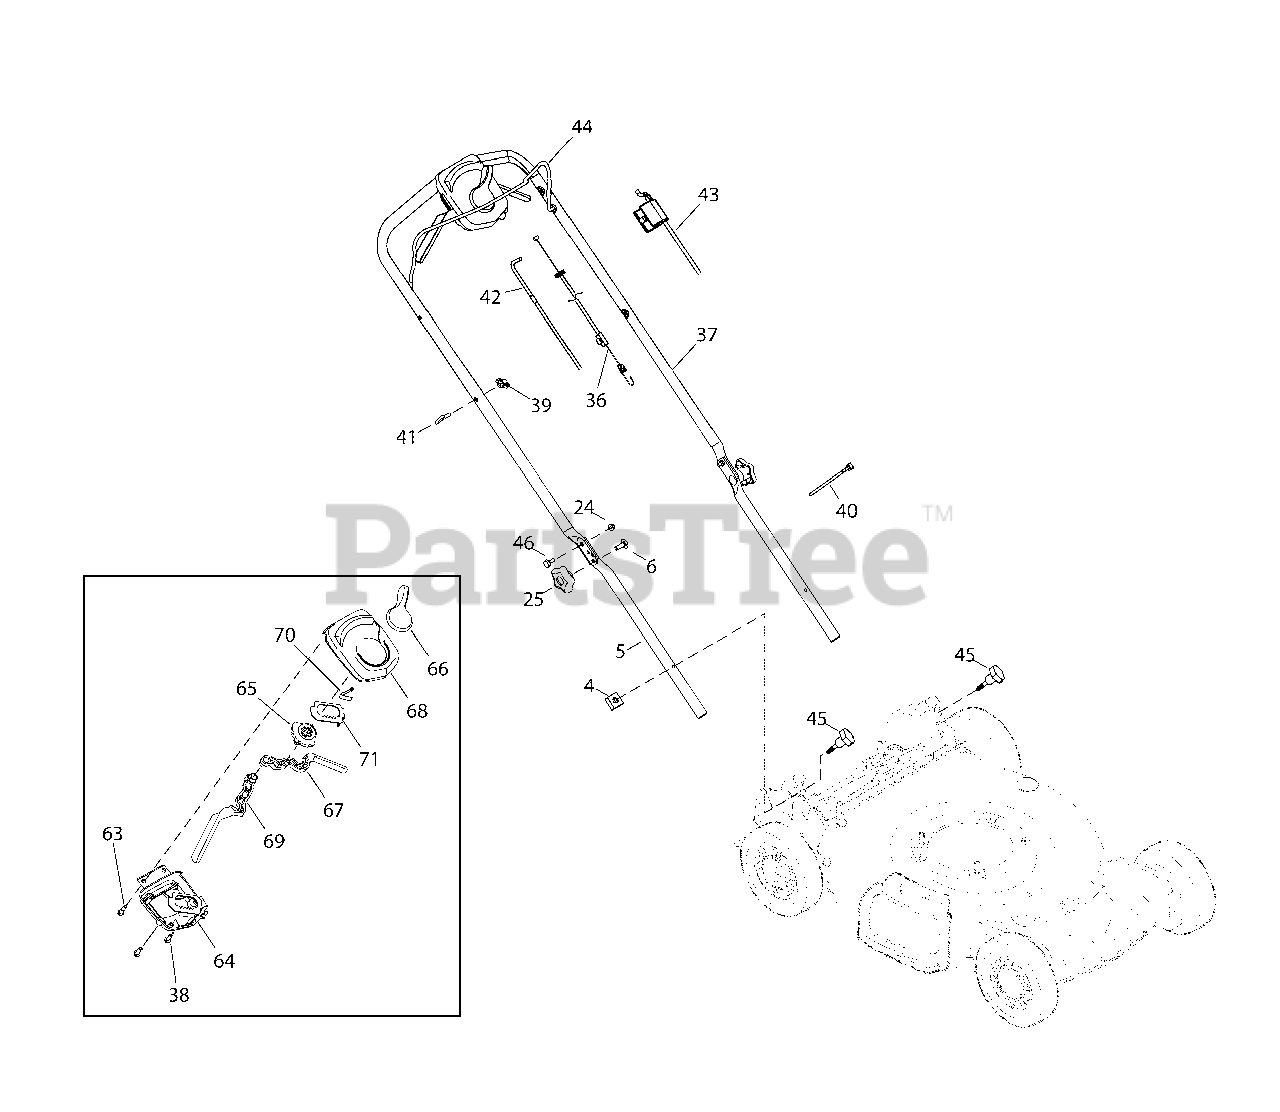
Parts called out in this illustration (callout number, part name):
4	NUT, Square, 1/4-20
5	HANDLE, Lower
6	BOLT, Carriage, 5/16-18 x 1, GR5
24	NUT, Nylock Flanged, 1/4-20
25	KNOB, Wing, 5/16-18
36	CABLE, Speed Adjustment
37	HANDLE, Upper
38	SCREW, 1/4-15X3/4, Self-Tapping, BZ
39	KNOB, 1/4-20
40	TIE, Self Lock
41	GUIDE, Rope
42	CABLE, Drive
43	CABLE, OPC Engine Brake
44	BAIL, Blade Control
45	NUT, Wing
46	BOLT, Shoulder, 1/4-20
63	SCREW, Shoulder, 1/4-15 x 1
64	HOUSING, Lower
65	ACTUATOR, Speed Adjust
66	LEVER, Speed Select
67	LEVER, Control, LH
68	HOUSING, Upper
69	LEVER, Control, RH
71	PLATE, Cable Adjust
